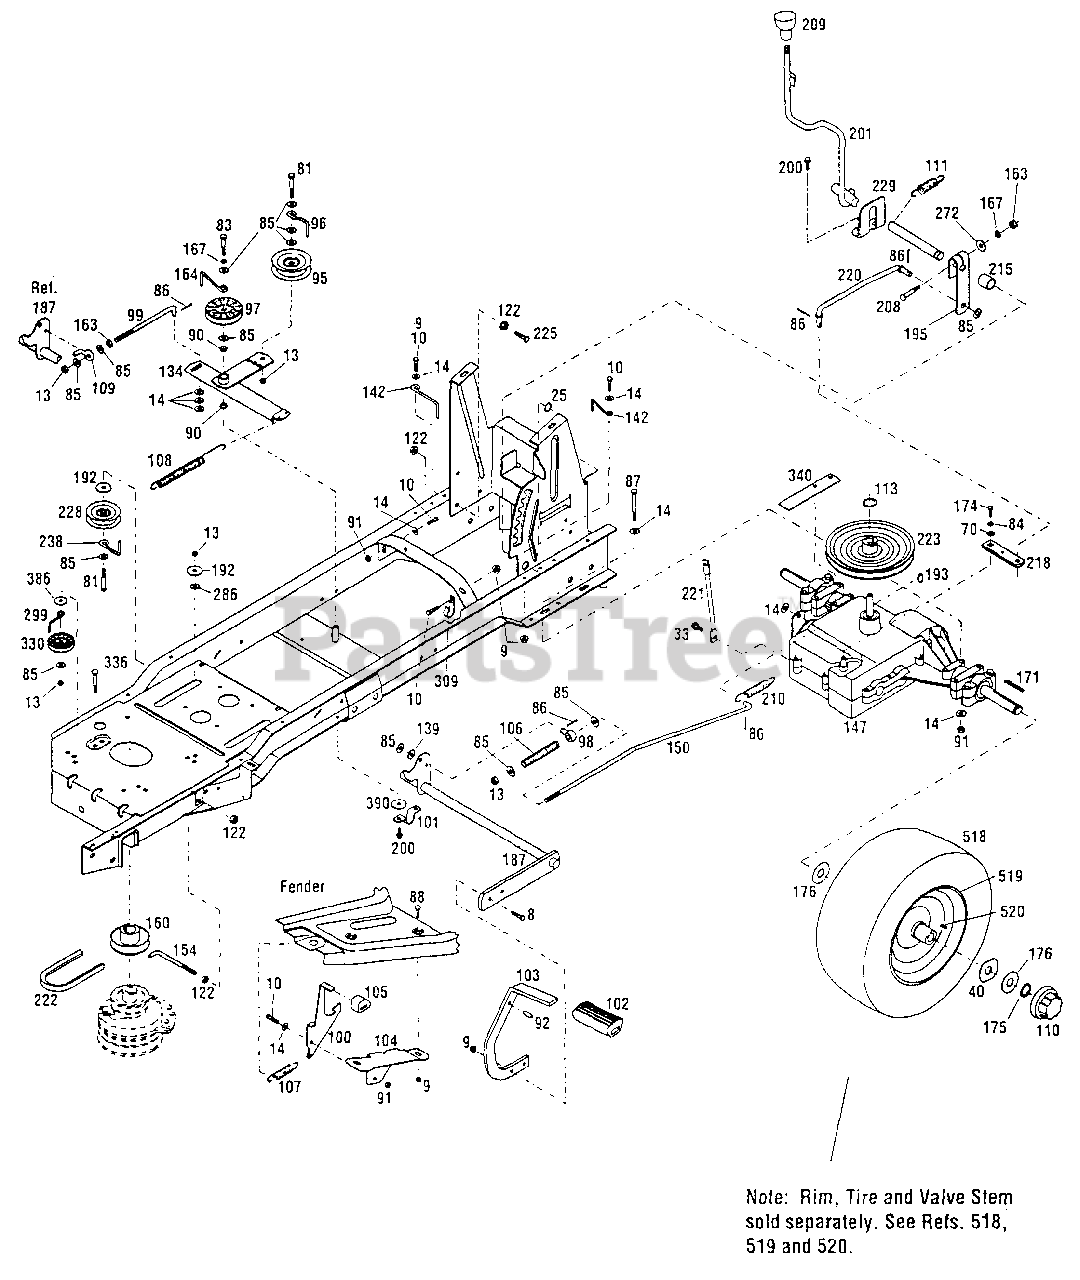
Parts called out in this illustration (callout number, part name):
8	Hex Head Capscrew, 5/16-18 x 1
9	Flange Nut, 5/16-18
10	Hex Head Capscrew, 5/16-18 x 3/4
13	Top Locknut, 3/8-16
14	Flat Washer, 5/16
25	Retaining Ring, 3/4
33	Flange Lock screw, 5/16-18 x 3/4
40	Special Washer, 3/4 x 2-1/2
70	Flat Washer, 1/4
81	Hex Capscrew, 3/8-16 x 2
83	Hex Capscrew, 3/8-16 x 1-3/4
84	Lock Washer, 1/4 SAE
85	Flat Washer, 3/8
86	Cotter Pin, 3/32 x 3/4
87	Hex Screw, 5/16-18 x 2-3/4
88	Carriage Bolt, 5/16-18 x 5/8
90	Nyliner Bushing
91	Locknut, 5/16-18
92	Drive Pin, 5/16 x 1
95	Idler Pulley
96	Belt Guide
97	Idler Pulley
98	Swivel
99	Clutch Rod
100	Brake Lock Latch
101	Clip, 3/4
102	Brake Pedal Pad
103	Brake Pedal
104	Brake Lock Bracket
105	Parking Brake Pedal Pad
106	Compression Spring
107	Extension Spring
108	Extension Spring
109	Pivot Rod
110	Hub Cap
111	Spring
113	Retaining Ring, 5/8
122	Flange Nut, 3/8-16
134	Idler Arm Assembly
139	Flat Washer, 3/8
142	Belt Guide
150	Brake Rod
154	Clutch Retainer
160	Engine Sheave
163	Hex Nut, 3/8-16
164	Belt Guide
167	Lock Washer, 3/8
171	Square Key, 3/16
174	Hex Screw, 1/4-28 x 1/2
175	Retaining E-Ring, 5/8
176	Flat Washer, 3/4 x 1-7/8
187	Brake Pedal Assembly
192	Flat Washer
193	Woodruff Key, 3/16 x 3/4
195	Shift Shaft Arm
200	Flange Lock screw, 5/16-18 x 3/4
201	Gear Shift Arm
208	Carriage Bolt, 3/8-16 x 2-1/4
210	Extension Spring
215	Spacer
218	Transmission Arm
220	Adjusting Rod
221	Transmission Support
223	Transmission Sheave
225	Screw, 3/8-16 x 1-1/4
228	Idler Pulley
229	Shaft Guide
238	Belt Guide
272	Special Washer, 3/8
286	Flat Washer
299	Belt Guide
309	J-Clamp
330	Idler Sheave
336	Carriage Bolt, 3/8-16 x 1-3/4
386	Flat Washer, 1/2
390	Flat Washer, 3/8
518	Tire, 20 x 8.00-8
520	Valve Stem
